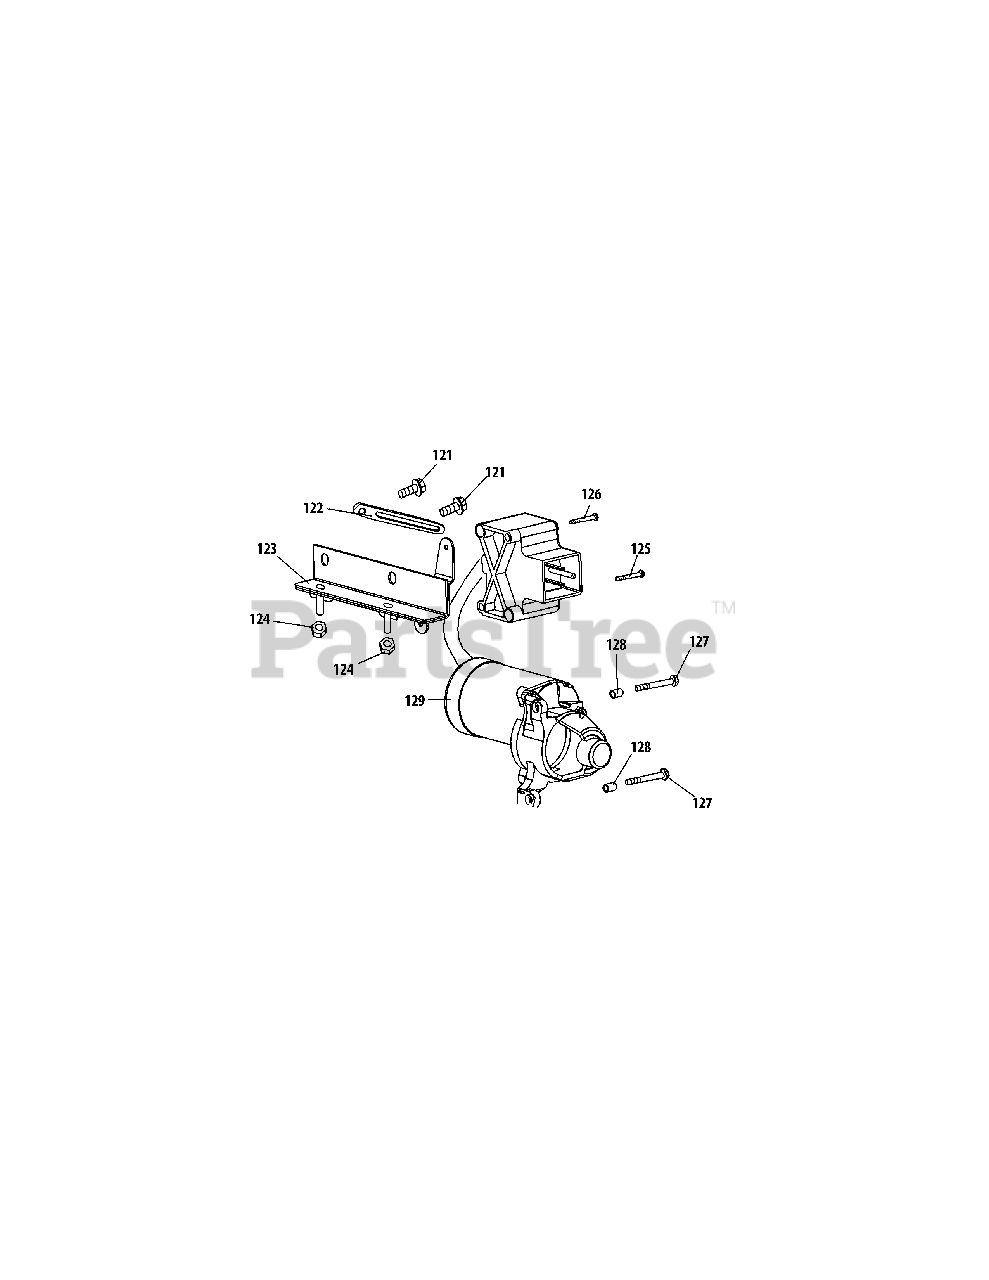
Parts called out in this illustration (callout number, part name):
121	Bolt M6×10
123	Switch Housing Mounting Bracket
124	Nut, M6
125	Bolt M4×55
126	Bolt M4×60
127	Bolt M6×32
128	Dowel Pin 8×8
129	Electric Starter
